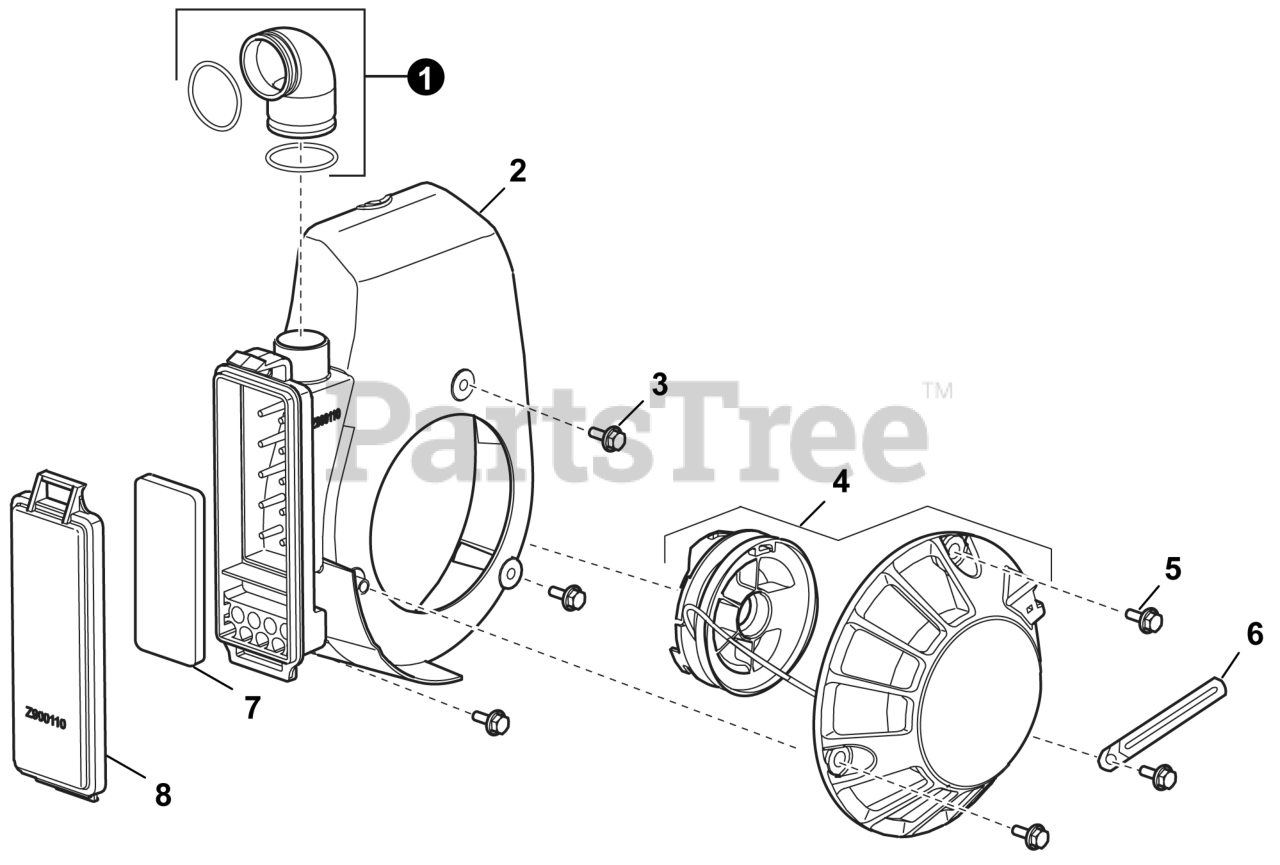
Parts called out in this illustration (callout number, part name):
1	TUBE, INTAKE
4	STARTER ASSY., RECOIL
7	FILTER, AIR
8	COVER, AIR FILTER
